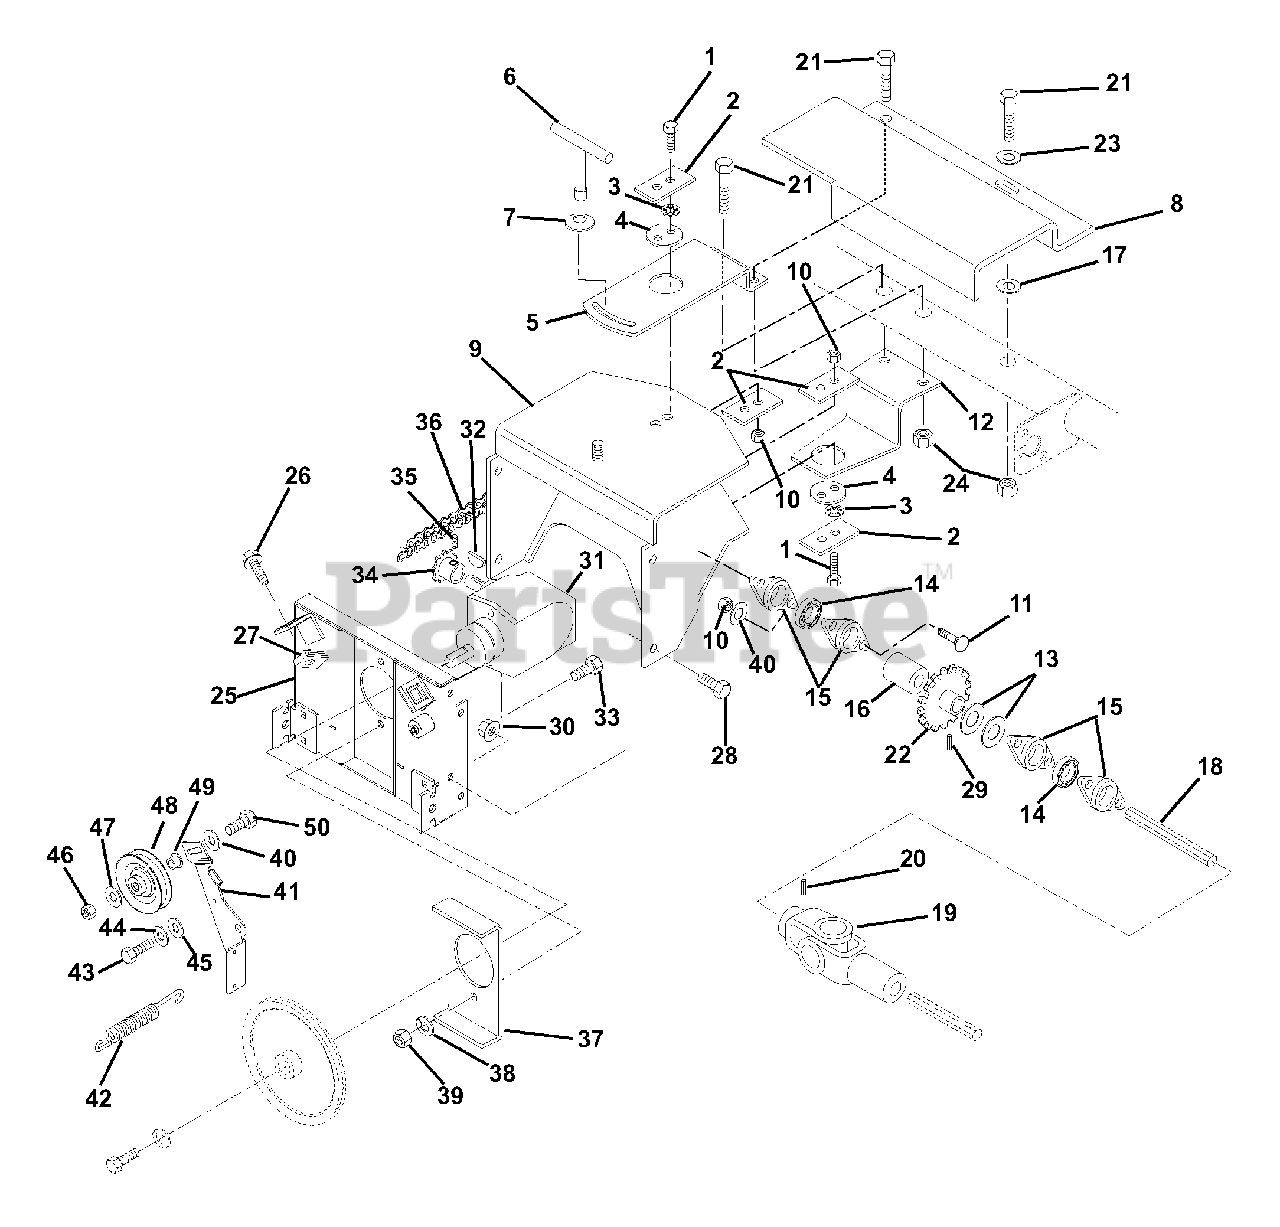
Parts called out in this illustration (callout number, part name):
1	@BLT-HEX .31-18X1.25 GR5 YWZC
2	RETAINER
3	@WSHR-LK-EXT.326X.599X.031YWZC
4	PIVOT CENTER
5	PLATE, TOP MOUNT
6	T-LOCK HANDLE
7	WASHER, CUPPED SERRATED, .375
8	GUARD, SHAFT
9	FRAME, ADAPTOR
10	@NUT-LK-CTR .31-18 YWZC
11	@BLT-RDHDSQNK .31-18X.75 G5YZ
12	PLATE, BOTTOM MOUNT
13	WSHR-FL-STL 1.015X1.500X.125
14	BRG-BALL .884HEXX52MMX1.07
15	BEARING FLANGE
16	SPACER 1.006X1.307X.500
17	WSHR-FL-STL .390X.88X.18 YWZC
19	JOINT, UNIVERSAL
20	PIN-ROLL .188X1.50
21	@BLT-HEX .38-16X3.25 GR5 YWZC
22	SPROCKET
23	@WSHR-FL-STL.406X.812X.065 YWZ
24	@NUT-LK-CTR .38-16 YWZC
25	PLATE, MOUNTING-BROOM
26	BLT-SERHFWH .38-16X.75 YWZC
27	NUT-RETNR .38-16 TINRMAN
28	@BLT-HEX .38-16X.75 GR5 YWZC
29	PIN-ROLL .188X1.75
30	@NUT-LK-CTR .38-16 YWZC
31	GEAR BOX ASSEMBLY
32	KEY-WDRF .188X.75X.313 SAE 9
33	@BLT-HEX .38-16X1.25 GR5 YWZC
34	SPROCKET
35	SCR-SET .25-20X.38 SKHCUPNL OH
36	ROLLER CHAIN #41 - 34 PITCHES
37	PLATE, STIFFENER
38	@WSHR-LK .38X.094 REG YWZC
39	@NUT-HEX .38-16 YWZC
40	@WSHR-FL-STL.38X.875X.083 YWZC
41	ARM, AUGER/BRAKE-HIGH W/LINING
42	SG-TENS .062X.56X8.0 WLD 11
43	@BLT-HEX .31-18X.75 GR5 YWZC
44	WSHR-LK .312X.097 HVY YWZC
45	WSHR-FL-STL .328X1.0X.094 YWZC
46	@NUT-LK-CTR .31-18 YWZC
47	@WSHR-FL-STL.344X.688X.065YWZC
48	IDLER
49	SPCR, BRG .315X.50X.688X.281
50	@BLT-HEX .31-18X1.25 GR5 YWZC
